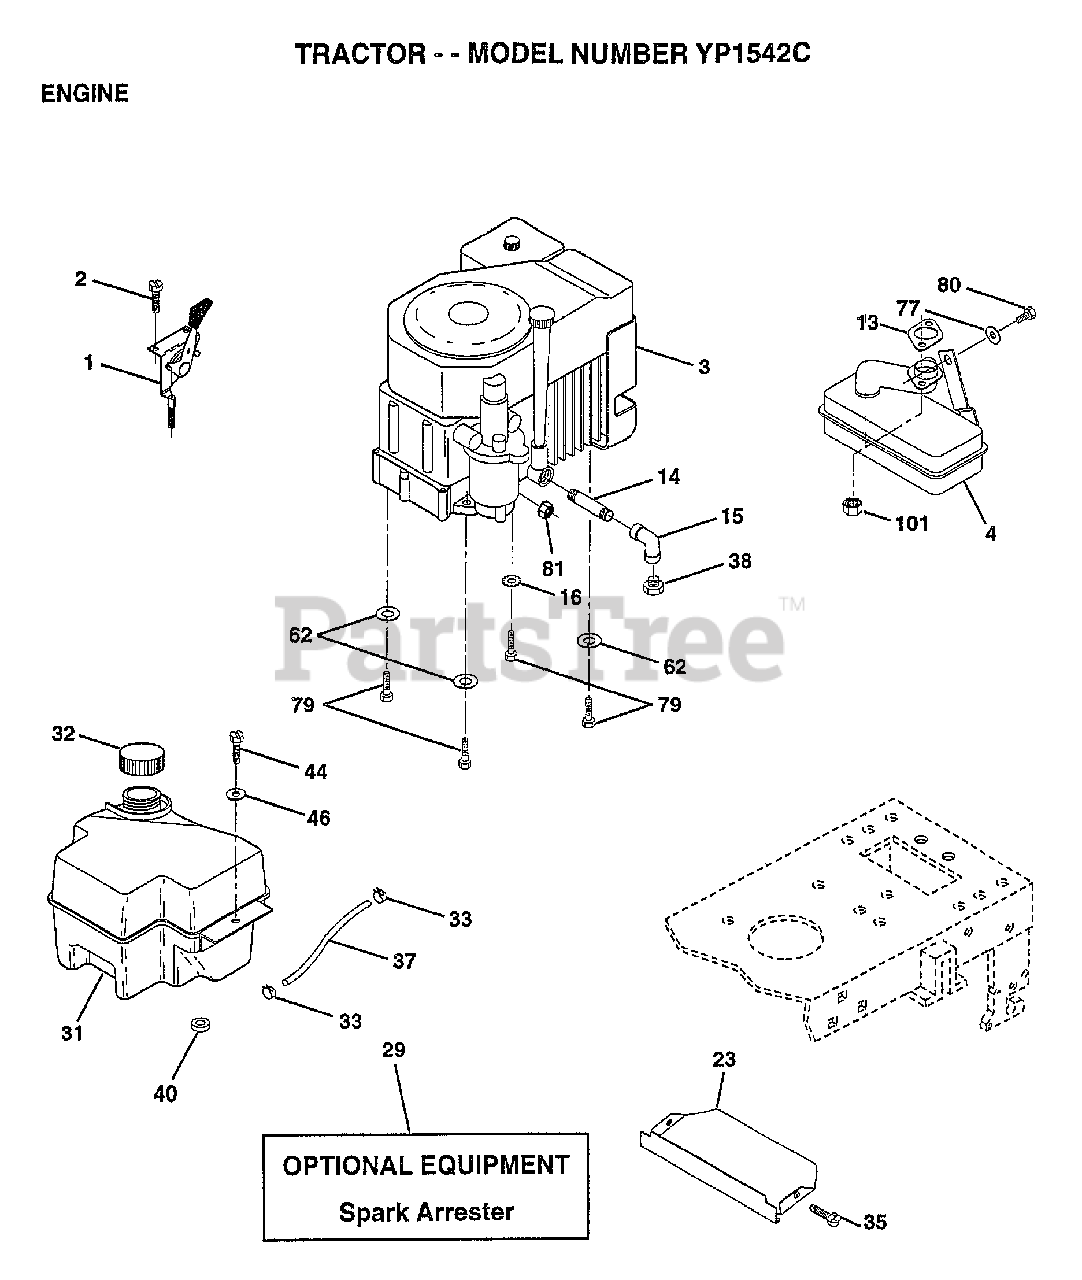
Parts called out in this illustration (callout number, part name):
1	CONTROL.THROTTLE/CHOKE
2	SCREW LT
4	MUFFLER
13	GASKET, EXHAUST MANIFOLD
14	PIPE NIPPLE
15	ELBOW
16	LOCKWASHER.5/16.E
23	SHIELD BRN/DBR GUARD
31	TANK.FUEL.FRONT.
32	CAP ASM FUEL
33	HOSE CLAMP
35	SCREW
37	LINE FUEL
44	SCREW HEX CRT
46	WASHER
62	LOCKWASHER
80	BOLT
81	NUT
101	NUT FLANGE M8-125
